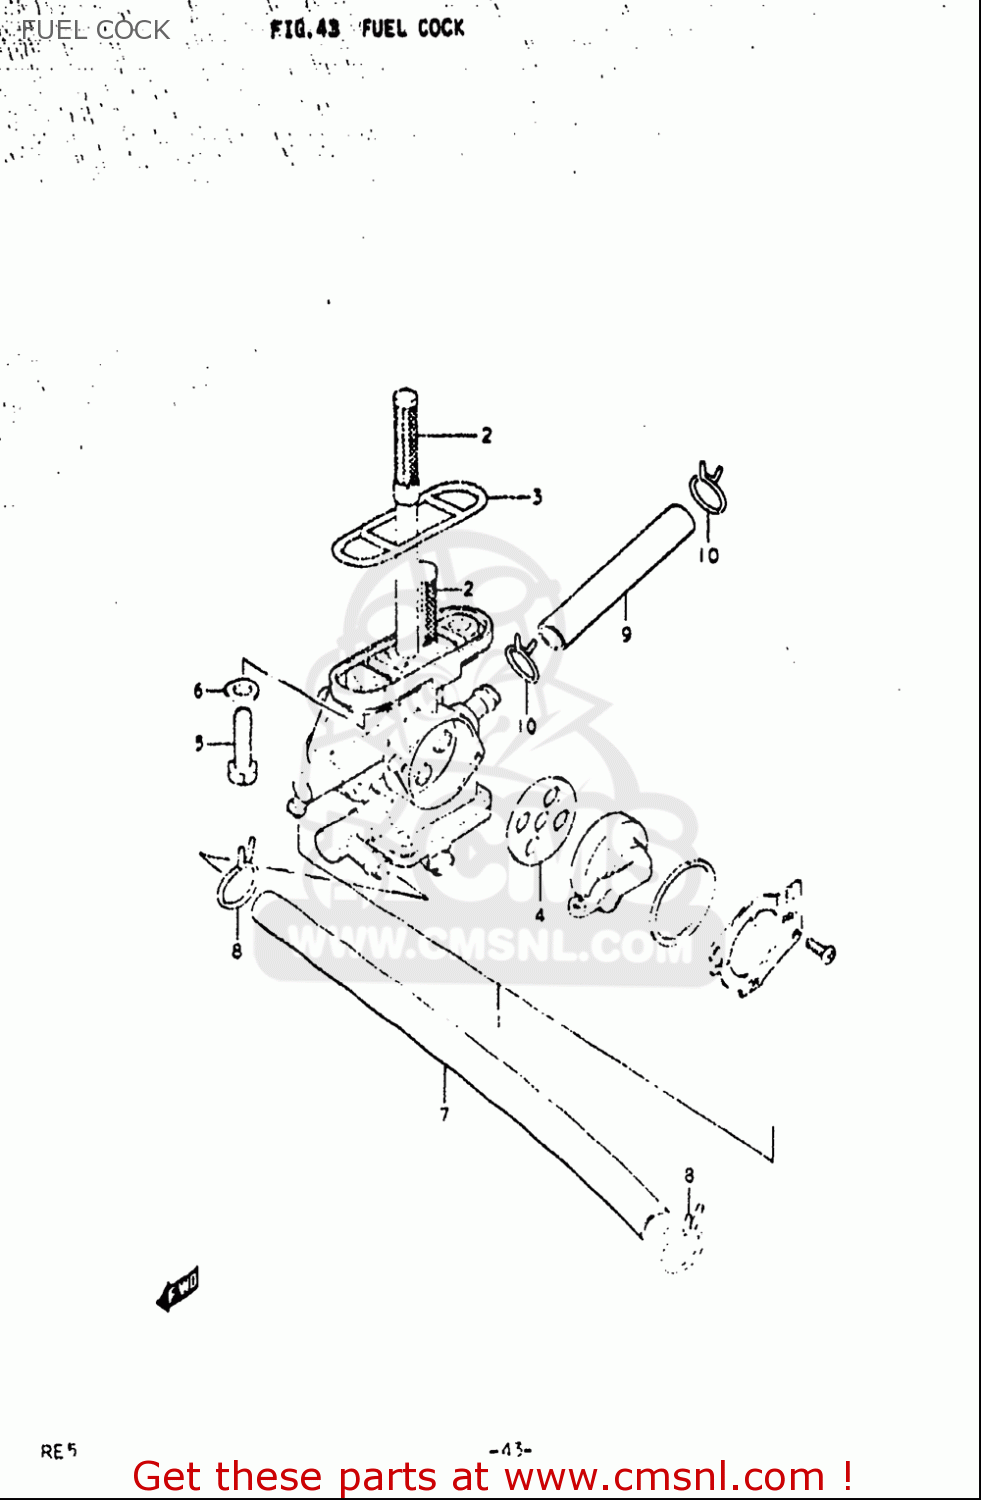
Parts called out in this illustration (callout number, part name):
2	FILTER
3	GASKET, FUEL COCK (NAS)
4	GASKET (NAS)
5	BOLT
6	GASKET(5.8X13X1.2) (NAS)
8	CLIP
10	CLIP
